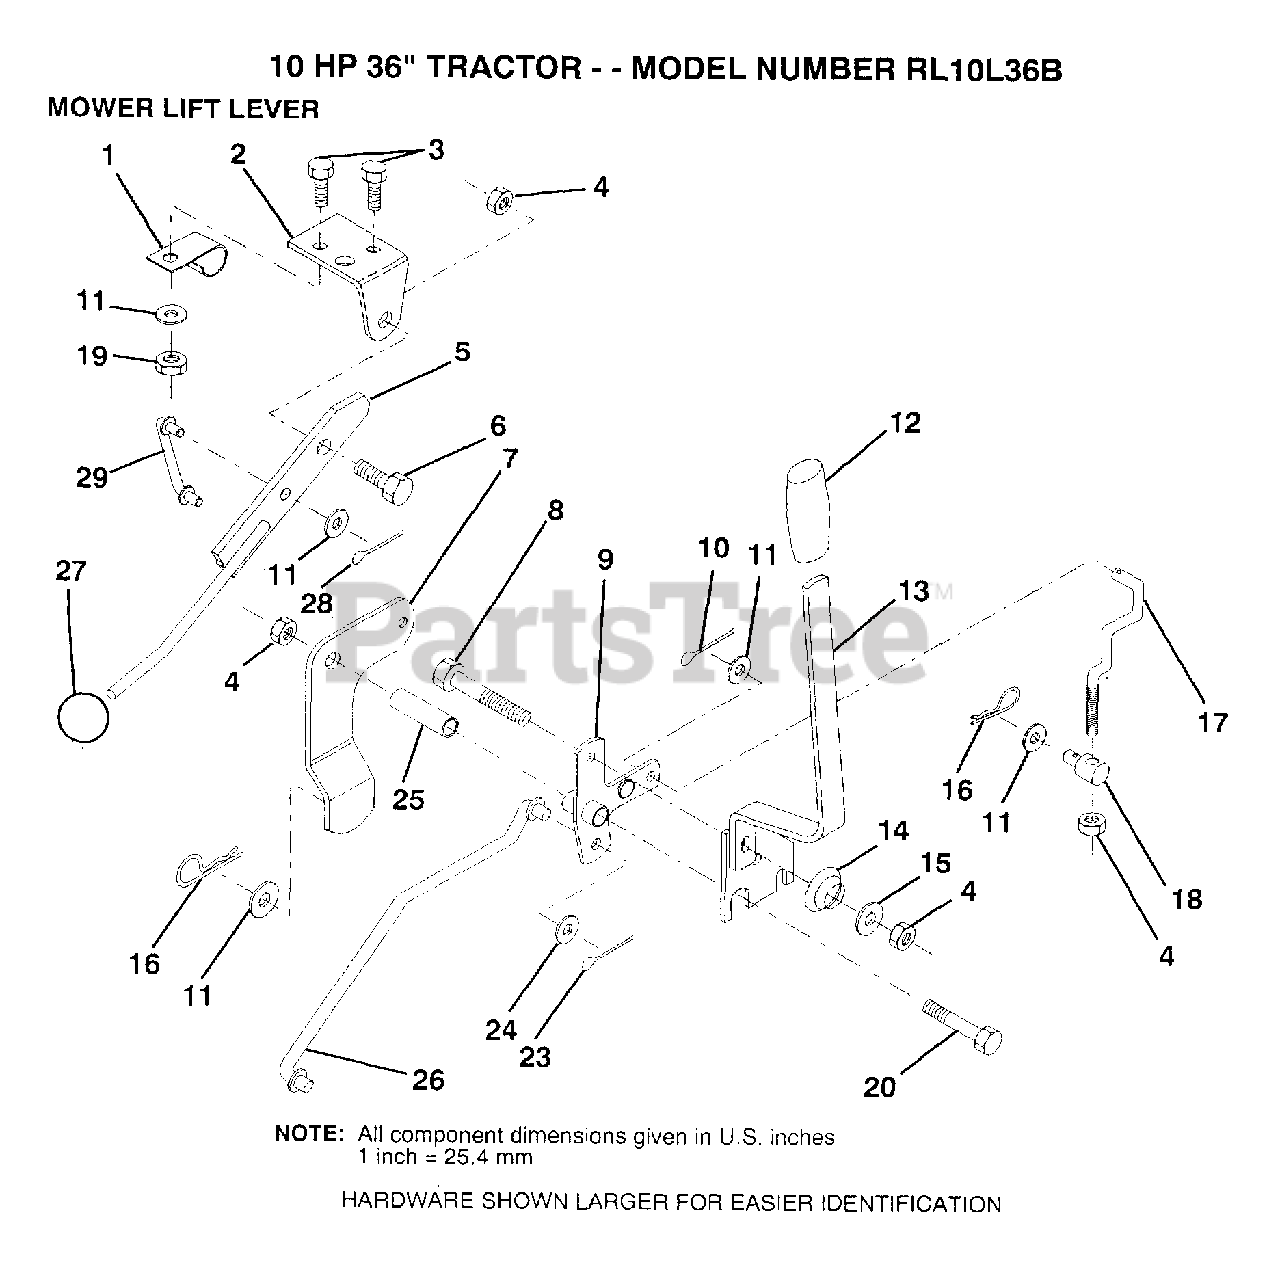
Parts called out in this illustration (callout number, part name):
1	"CLIP,INSULATOR"
2	BRKT CLUTCH
3	BOLT
5	CLUTCH LEVER AS
6	"BOLT, SHOULDER LT"
7	MWR CLUTCH ARM AS
8	BOLT
9	"BELLCRANK,LIFT"
10	COTTER PIN
11	WASHER
13	HANDLE.ASM.LIFT
14	SPRING COMPRESSIO
15	WASHER T
16	SPRING.RETAINER
17	"LINK,LIFT FRT"
18	TRUNION
20	BOLT
23	PIN COTTER 1/8
25	TUBE SPACER
26	"ROD,MOWER LIFT "
27	KNOB T(3/8 HOLE)
29	CLUTCH LINK
